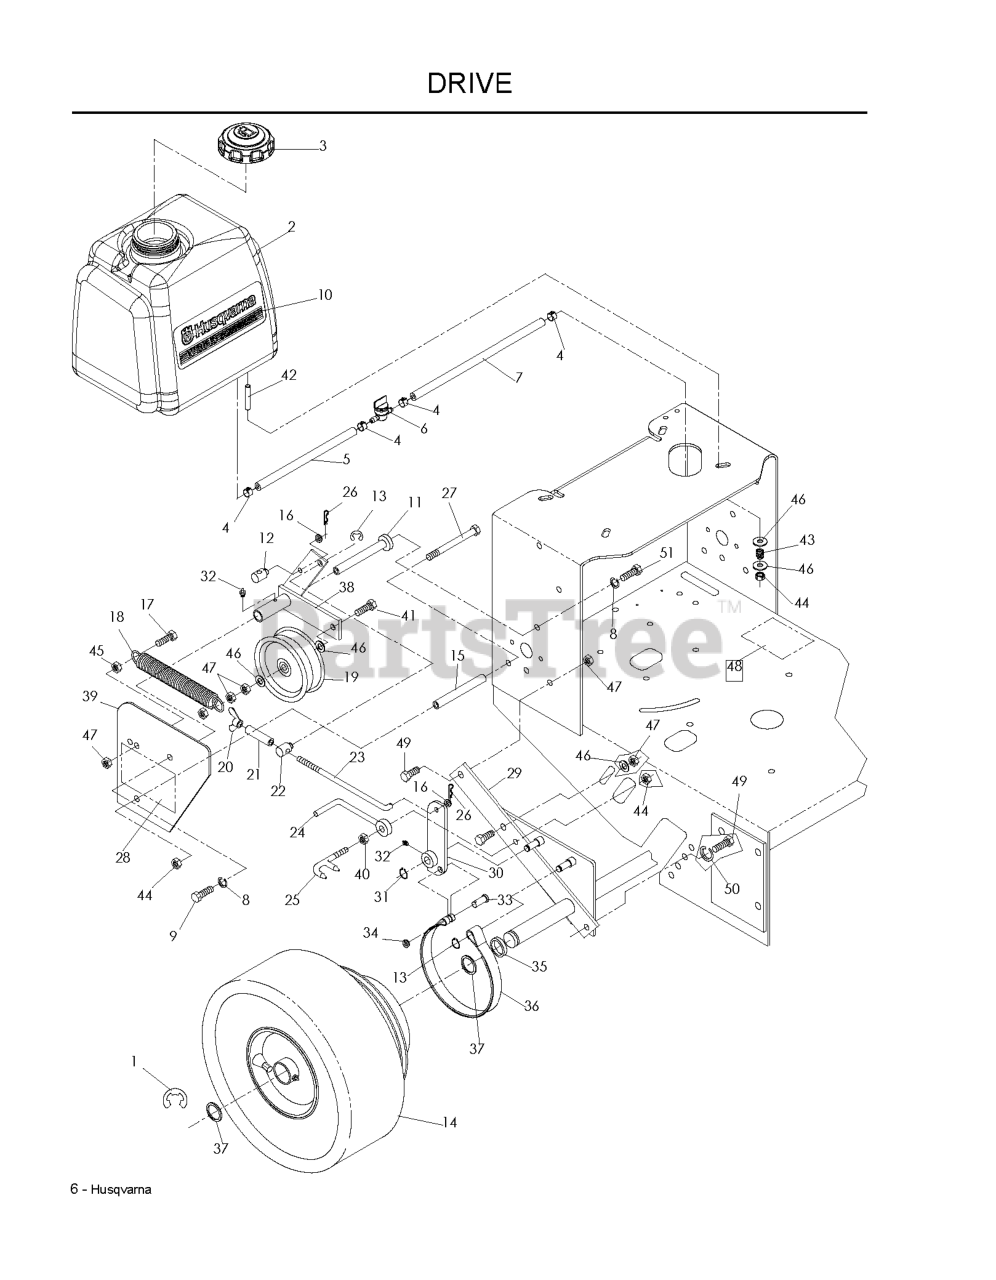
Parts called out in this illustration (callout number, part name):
1	E-RING 1"
3	FUEL CAP ANTI-SPLASH
4	HOSE CLAMP
5	GAS LINE 10"
6	FUEL VALVE
7	FUEL LINE 14"
8	WASHER.LOCK.HVY.HLCL.SPR.5/16
9	HCS 5/16C X 1
10	DECAL, W3613
10	DECAL, W3213
10	DECAL, W4815
11	SHOULDER PIVOT TUBE
12	SWIVEL (SHORT)
13	E RING 3/8"
14	WHEEL ASM
15	SPACER, LONG
16	WASHER 5/16 FLAT
17	HCS 3/8C X 1 1/4 GR5
19	PULLEY, IDLER
20	WINGNUT, 5/16C NYLOC
24	BELT GUIDE
25	SCRAPER (36 & 48)
25	SCRAPER
26	HAIRPIN #2
27	HCS 5/16C X 5
28	DECAL, CRN H 3-1/8 SILVER
29	AXLE WELDMENT (32)
29	AXLE WELDMENT (36 & 48)
30	BRAKE ARM, RIGHT
30	BRAKE ARM, LEFT
31	E-RING 1/2 (2 2)
32	ZERK
33	CLEVIS PIN
34	NUT 3/8 PALNUT RTNG BLK PHOS
36	BRAKE BAND
37	MACHINE BUSHING
38	IDLER PLATE, RIGHT
38	IDLER PLATE, LEFT
40	NUT 5/16C WHIZ
41	TAPBOLT, 3/8C X 3
42	STUD, 5/16C
44	NUT 5/16C CENTERLOCK
45	NUT 3/8C WHIZ
46	WASHER 3/8 FLAT
47	NUT 3/8C CENTERBLOCK
48	DECAL, PROP. 65
49	HCS 3/8-16X1.GRD.5.ZD
50	SLW 3/8 STD
